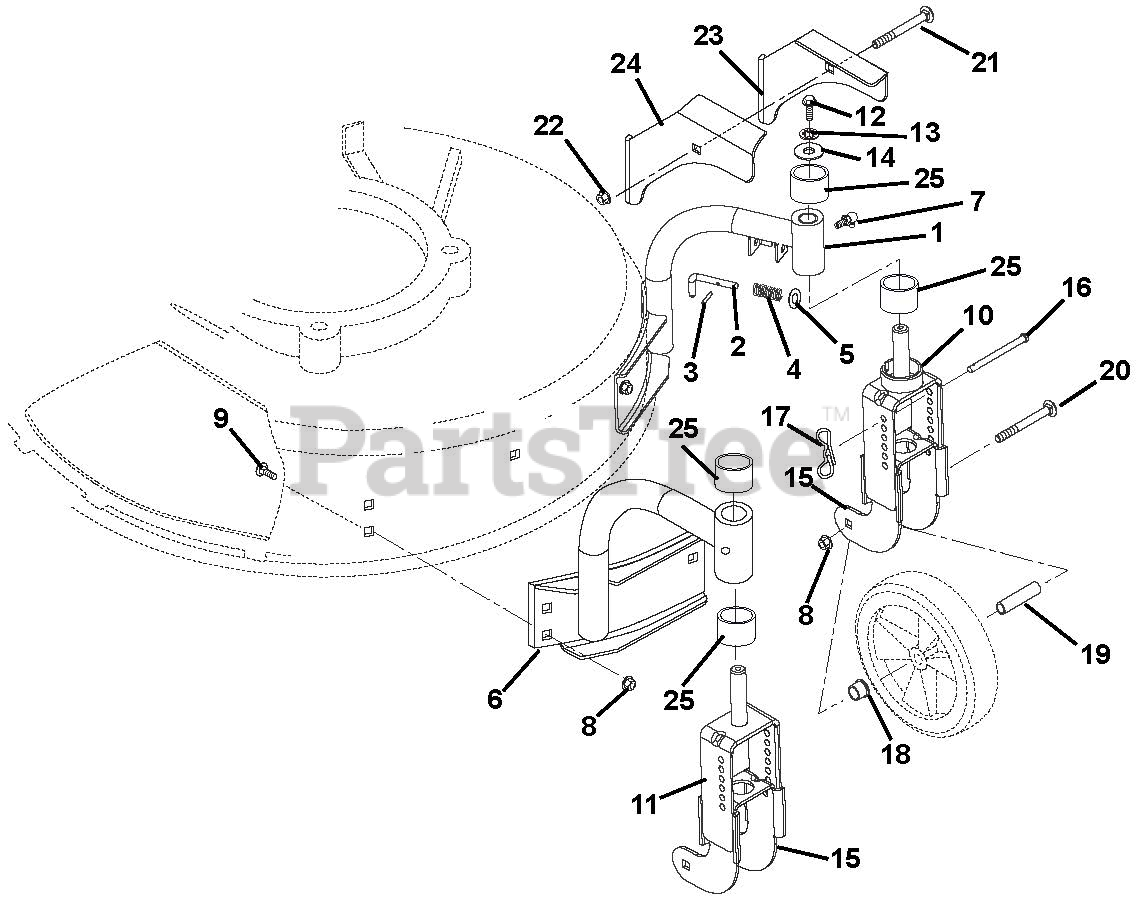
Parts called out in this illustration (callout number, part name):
1	WELDMENT, LH MOUNT
2	PIN, LOCKOUT
3	PIN-ROLL .093X.50
4	SPRG, COMP--SWVL LOCKOUT
5	@WSHR-FL-STL.281X.62X.065 YWZC
6	WELDMENT, RH MOUNT
7	FTG-LUBE .25-28X.256 YWZC
8	@NUT-LK-TOP-FLG .31-18 YWZC
9	@BLT-RDHDSQNK .31-18X.50 G5YZ
10	YOKE, OUTER LH
11	YOKE, RH OUTER
12	@BLT-HEX .25-20X.75 GR5 YWZC
13	WSHR-LK .250X.077 HVY YWZC
14	WSHR-FL-STL .281X1.000X.063
15	YOKE-INNER
16	PIN, HEIGHT ADJUSTMENT
17	PIN, BOW TIE LOCKING COTTER
18	BSHG-FLG .500X.625X.500X.750
19	SPCR, WHEEL .385X.500X2.00
20	BLT-RDHDSQSHNK.31-18X2.75G2YWZ
21	@BLT-RDHDSQNK .25-20X1.50 G5YZ
22	@NUT-SPNLK-FLG .25-20 YWZC
23	BRACKET, HOOD CABLE--LH
24	BRACKET, HOOD CABLE WELDMENT
25	BSHG-SLV .625X.750X.500 BR
26	@WSHR-FL-STL.250X.56X.049 YWZC
27	@PIN-CTR .09X.50 EXTPRSQCT YWZ
